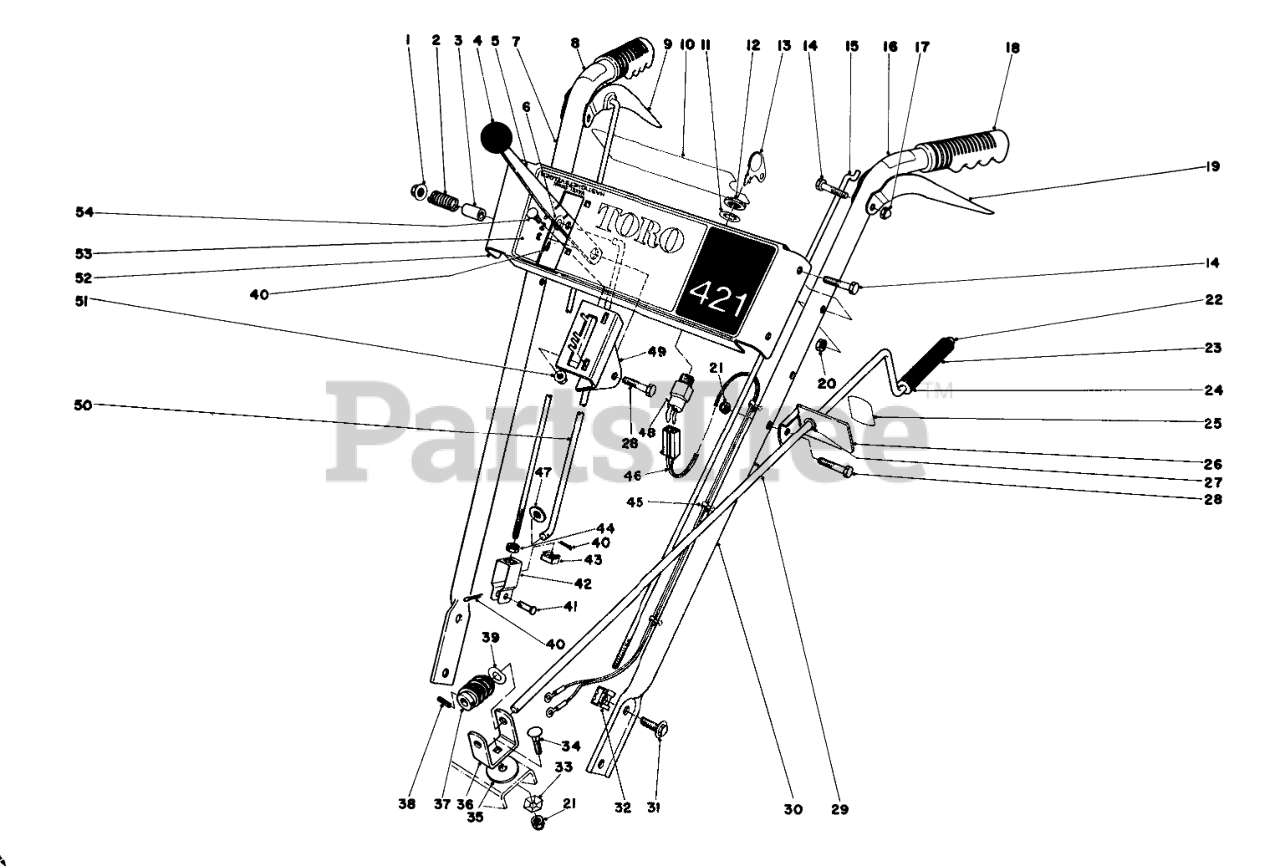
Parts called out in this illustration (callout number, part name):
1	NUT-HF
2	SPRING
3	Spacer-Speed Control
5	SPEED SELECTOR B
6	WASHER-FLAT
7	Handle Ring
8	Decal-Auger Drive
9	Lever-Auger Control
10	Decal-Escutcheon Back
11	WASHER-TOOTH, INTERNAL
12	NUT-HH
13	Key
14	SCREW-HH
15	Link Upper
16	Decal-Wheel Drive
17	NUT-CAP
18	Grip
19	Lever-Traction Control
20	NUT-LOCK, CONE
21	NUT-LOCK, NI
22	RETAINER-PUSH ON
23	CHUTE CONTROL GRIP
24	WASHER-FLAT
25	CHUTE DECAL
26	Bracket-Chute Control Mtg. (Incl. Ref. #25 & 27)
27	Bushing
28	SCREW-HH
29	ROD CHUTE CONTROL
30	Handle Left
31	SCREW-HHF
33	216 Washer
34	BOLT-CARR
35	WASHER
36	WORM BRACKET
37	GEAR-WORM, CHUTE
38	PIN-SPRING
39	WASHER-SPRING
40	PIN-COTTER
41	PIN-CLEVIS
42	CLEVIS
43	NUT-RETAINED
44	NUT-JAM
45	TIE-CABLE
46	WIRE HARNESS
47	WASHER-PLAIN
48	SWITCH-ON / OFF
49	Mount-Speed Selector
50	ROD-SELECTOR, SPEED
51	NUT-HHF
52	Panel-Escutcheon
53	Decal-Escutcheon
54	SCREW-CARRIAGE
